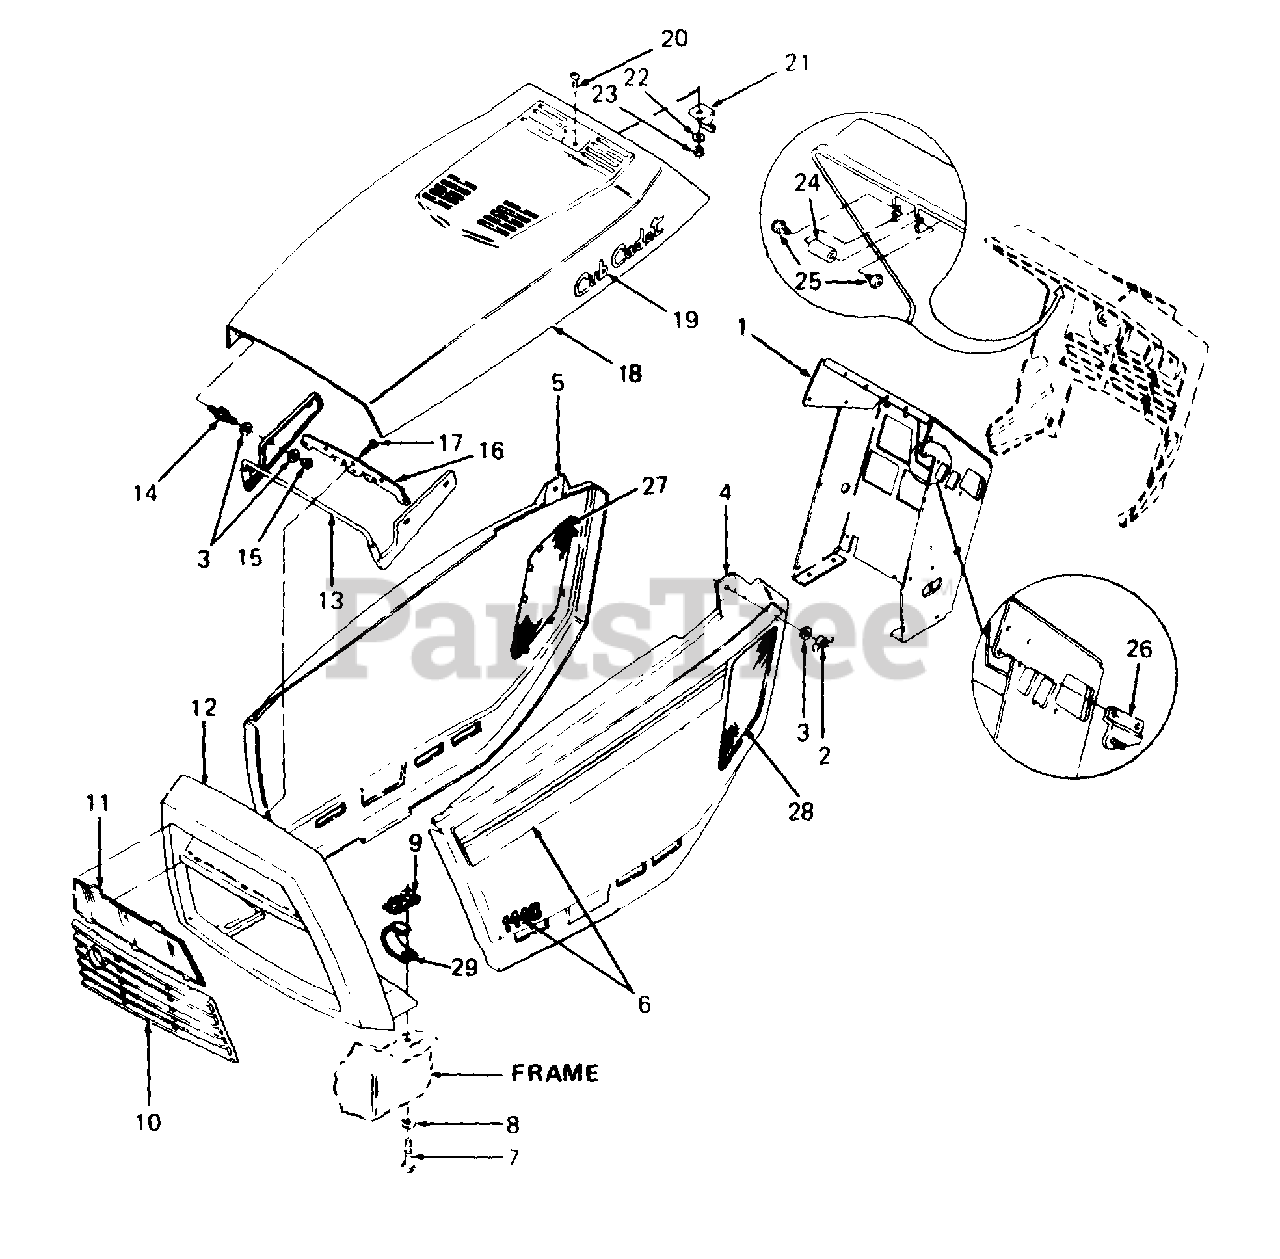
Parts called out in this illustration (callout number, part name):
3	Washer, Flat, .251 X .62 X .052 Thk
4	Panel, LH Side
5	Panel, RH Side
6	Graphics Kit, LH Side Panel
7	Screw, Hex Cap, 5/16-18 X 1.0 Lg GR5
8	Washer, Lock, 5/16
9	Retainer, Grille Housing
10	Grille, Insert
11	Grille, Lens
12	Grille Hsg
15	Nut, Hex Patch Lock, 1/4-20
18	Hood
19	Graphic, Cub Cadet Script w/Studs
20	Screw, Truss Hd, #8-32 X .38 Lg
21	Clip, Hood Latch
22	Washer, Flat, .16 X .38 X .045 Thk
23	Nut, Hex Keps, #8-32
24	Pin, Latch
25	Screw, Phillips Hd Truss Mach, 1/4-20 X .50 Lg
